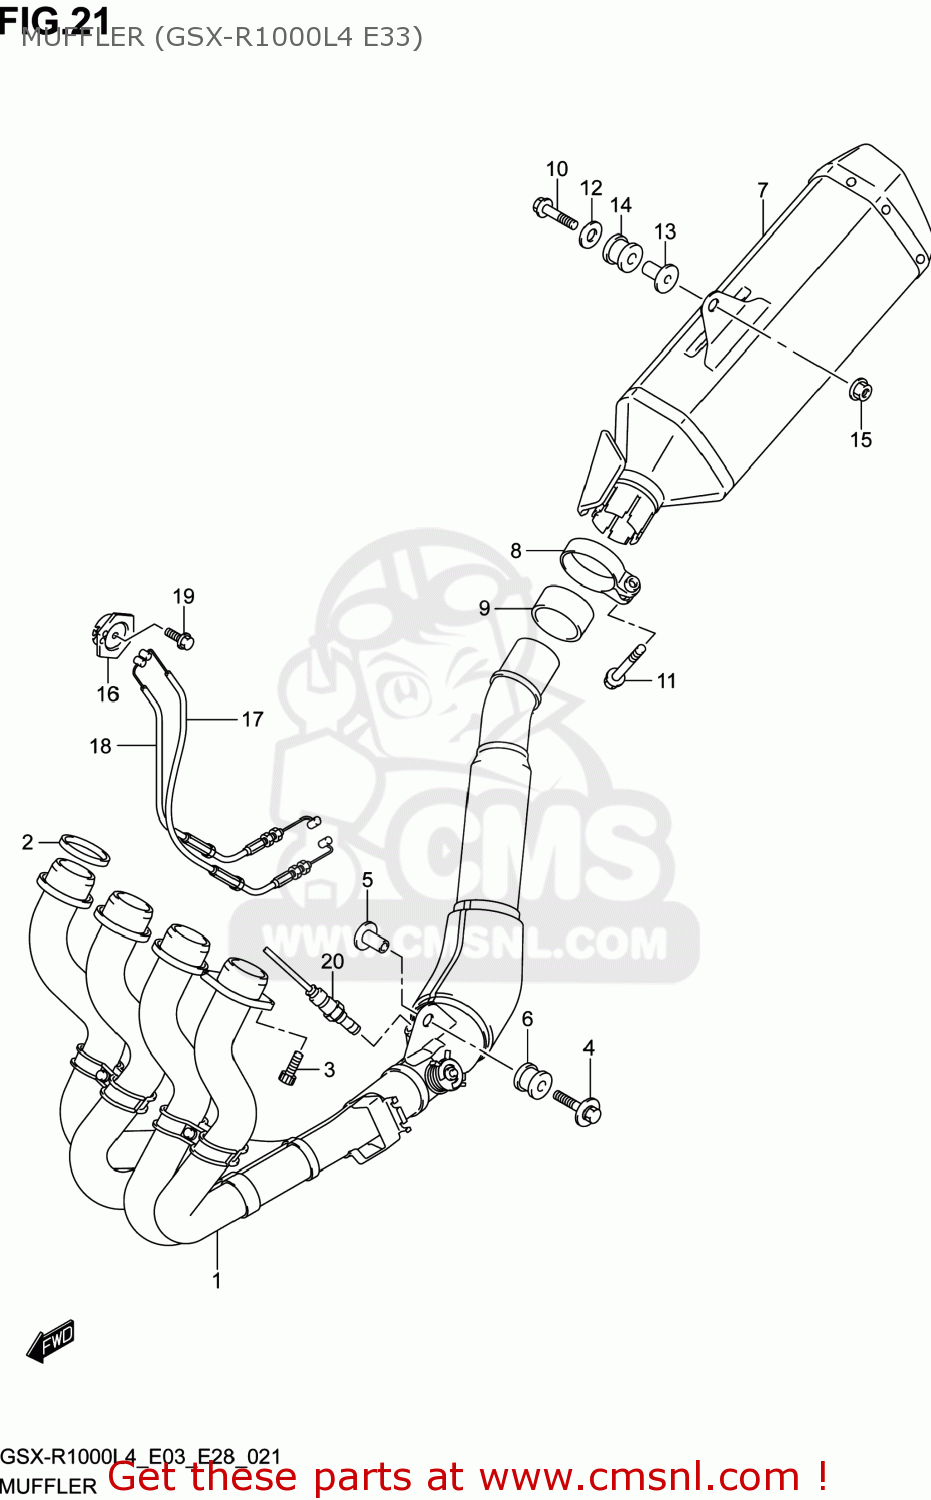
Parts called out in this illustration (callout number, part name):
1	EXHAUST
2	GASKET,EXHAUST PIPE (NAS)
3	BOLT
4	BOLT(8X45)
5	SPACER(8.6X12X24.2)
6	CUSHION
7	BODY,MUFFLER
8	CLAMP,MUFFLER CONNECTOR
9	CONNECTOR,MUFFLER
10	BOLT(8X45)
11	BOLT(8X40)
12	WASHER(8.5X28X1.5)
13	SPACER(8.6X12X24.2)
14	CUSHION
15	NUT
16	PULLEY,CONTROLLER
17	CABLE,EXHAUST VALVE NO.1
18	CABLE,EXHAUST VALVE NO.2
19	BOLT
20	SENSOR,OXYGEN
